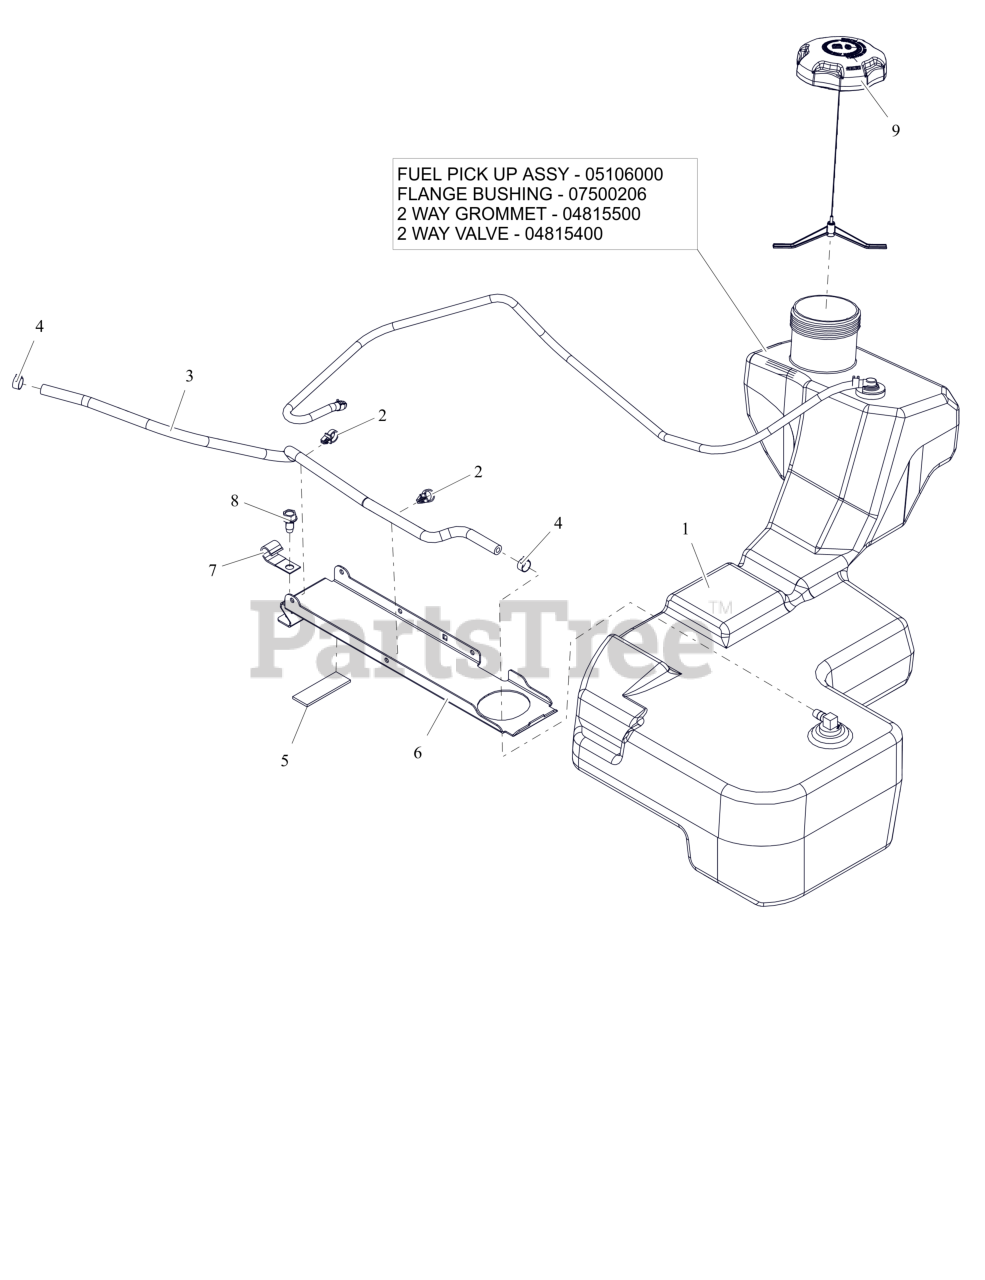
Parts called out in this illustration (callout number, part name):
1	ASM, FUEL TANK-HD
1	ASM, HD FUEL PICK-UP
1	BSHG-FLG .375X1.062X.625 NITR
1	GROMMET, 2-WAY
1	VALVE, 2-WAY
2	ROUTING CLIP (1/2" ID)
3	1 INCH OF HOSE, .25 LOW-PERM BULK GAS
4	CLAMP, FUEL LINE
5	PAD,RBR 1.0"X3.0" W/ADHESIVE
6	BRKT, FUEL TANK HOLD DOWN
8	SCR,TAP .375-16X.75 HWH TR ZCC
9	CAP, FUEL - 3.50 RATCHET INLET VENT
